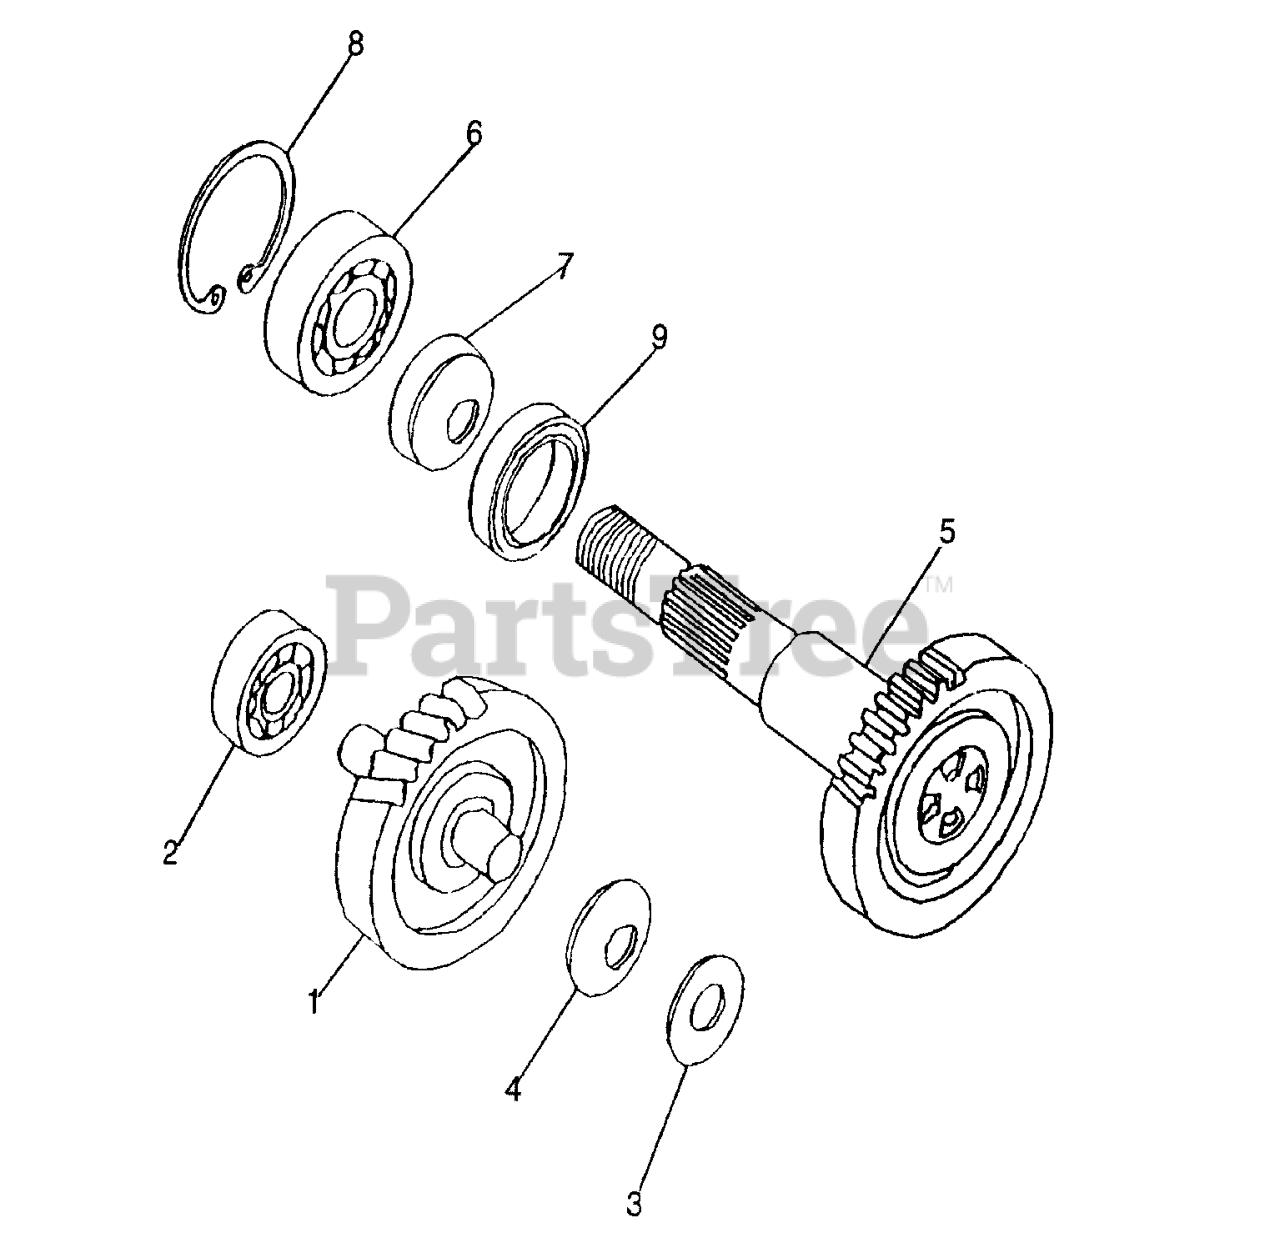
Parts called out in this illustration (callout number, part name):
1	SHAFT, IDLE
2	BEARING 6201
3	PLATE WASHER 12
4	WASHER, CONICAL
5	SHAFT, REAR BOX
6	NEEDLE BEARING
7	OIL SEAL
8	CIRCLIP
9	NEEDLE BEARING
